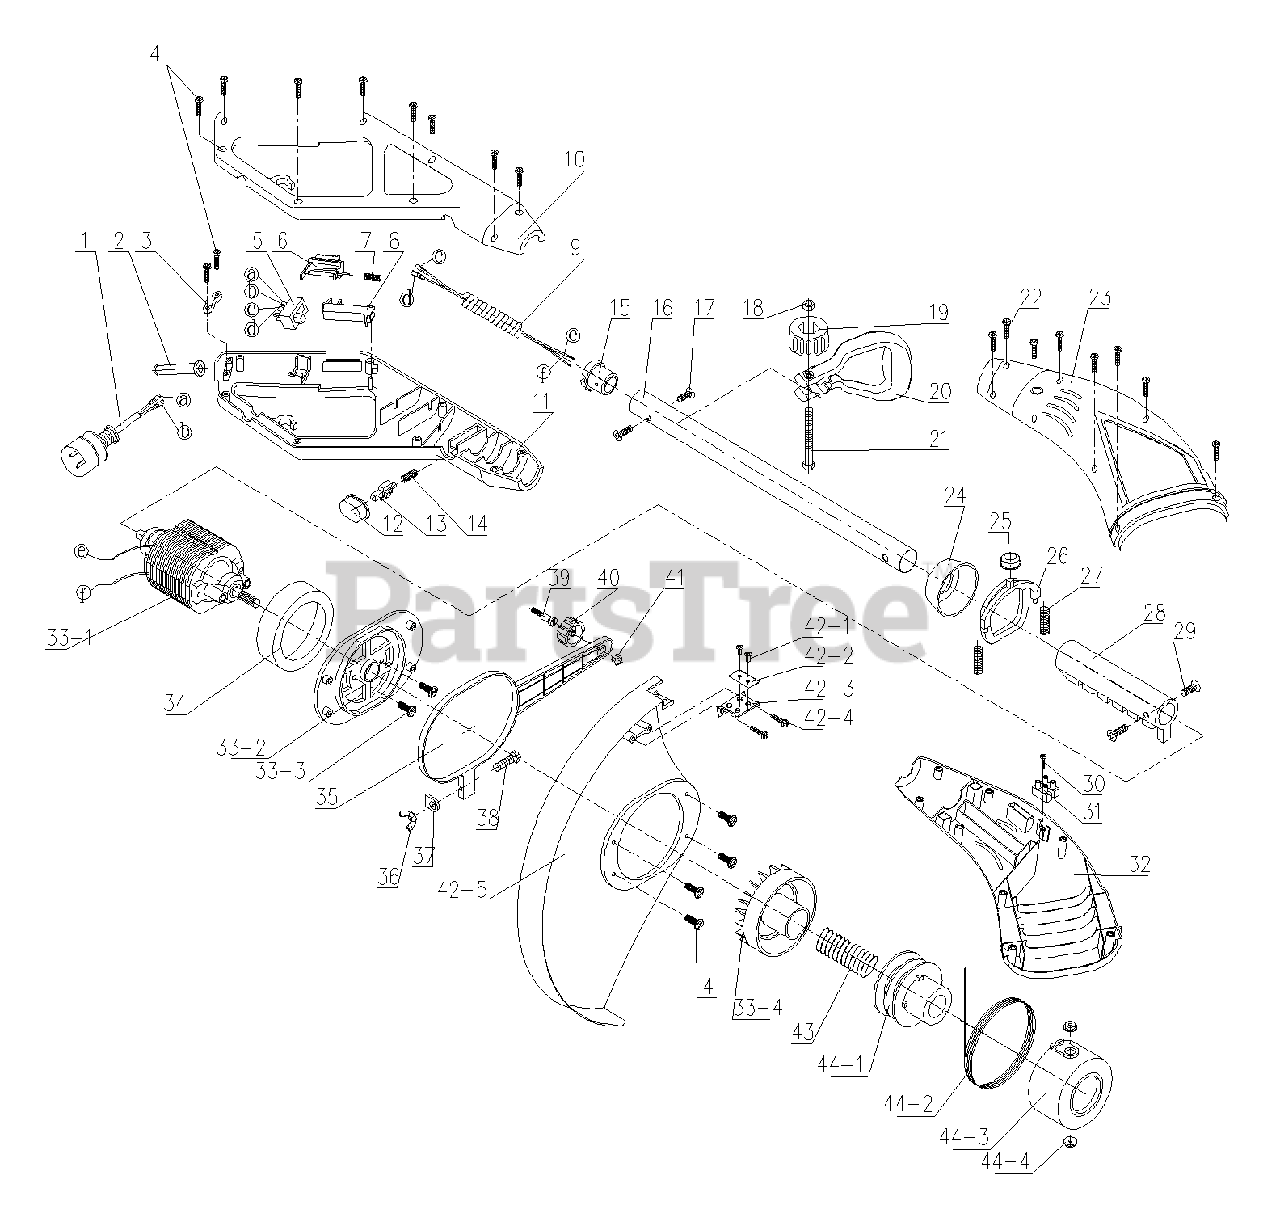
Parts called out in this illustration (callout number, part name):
1	POWER CORD
2	CORD GUARD
3	PLATE (PRESSING CORD)
10	UPPER HANDGRIP (R)
11	UPPER HANDGRIP (L)
15	JOINT PIPE
16	CENTRAL TUBE
20	CENTRAL HANDGRIP
23	HOUSING (R)
26	FIXED RING
28	EXPANDING RING
31	TERMINAL BLOCK
32	HOUSING (L)
33	MOTOR ASS'Y
34	CUSHION RING
35	CUSHION RING
39	SHAFT PIN
42	SHIELD ASS'Y
44	SPOOL CARRIER ASS'Y
